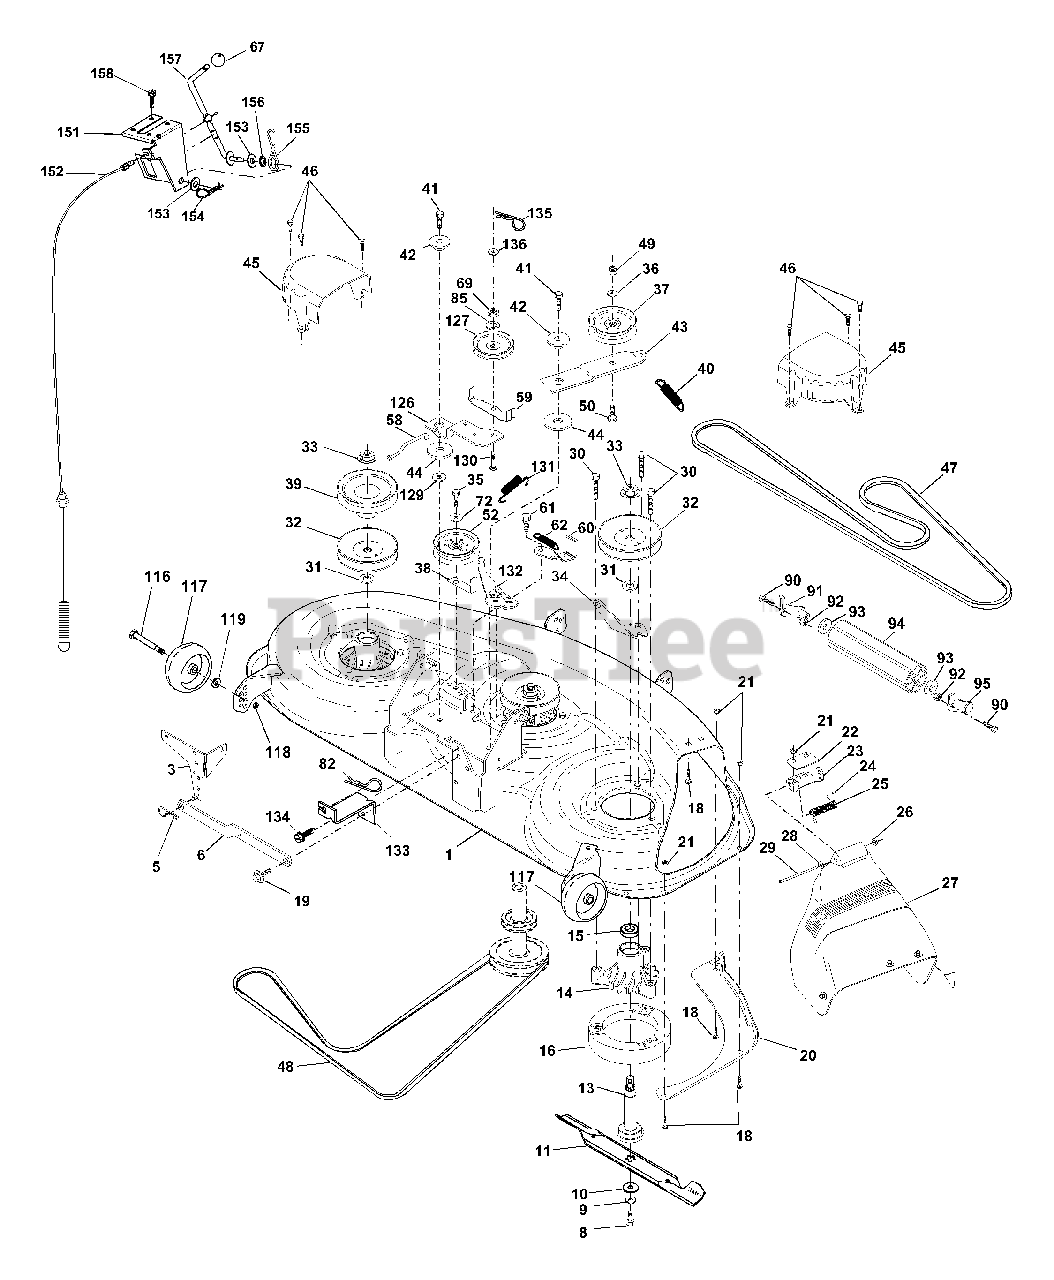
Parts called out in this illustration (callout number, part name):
1	Deck Asm., Mower 46"
3	Bracket Asm., Sway Bar
5	Retainer Spring
6	Arm, Suspension, Rear (Sway Bar)
8	Bolt, Patched 3/8-24 x 1-1/4 Gr. 8
9	Washer, Lock Hvy., Unplated 3/8
10	Washer, Hard Blade, Mower Vented
11	Blade Hi-Perf 46"
13	Shaft Asm. w/Lower Bearing
14	Housing, Mandrel
15	Bearing, Ball, Mandrel
16	Stripper, Mower Round
18	Bolt, Carriage 5/16-18 x 5/8
19	Bolt, Hex Head, Shoulder 5/16-18
20	Baffle, Vortex Mower 46"
21	Nut, Crownlock 5/16-18 UNC
22	Stiffiner, Bracket
23	Bracket, Deflector
24	Cap, Sleeve
25	Spring, Torsion, Deflector
26	Nut, Push
27	Shield, Deflector Mower
28	Washer 11/32 x 5/8 x 16 Ga.
29	Rod, Hinge
30	Screw, Thdroll Washer Head
31	Washer, Spacer Mower Vented
32	Pulley, Mandrel
33	Nut, Flg. Top Lock Cntr. 9/16
34	Anchor, Spring Deck 46"
35	Screw, Thdroll 3/8-16 x 1-3/4 Tytt
36	Washer 13/32 x 1 x 16 Ga.
37	Pulley, Idler, Flat
38	Keeper, Belt, Idler
39	Pulley, Idler, Driven
40	Spring, Secondary 44/46/50 Vent
41	Screw 3/8-16 x 1-1/4
42	Spacer, Retainer
43	Arm, Idler Secondary
44	Washer,Hardened
45	Cover, Mandrel Deck
46	Screw, Thdroll. 1/4-20 x 5/8
47	V-Belt, Mower, Secondary
48	V-Belt, Mower, Primary
49	Nut, Crownlock 3/8-16 UNC
50	Bolt, Carriage 3/8-16 x 1-1/2 Gr. 5
52	Pulley Idler
58	Rod Brake 46"
59	Guide Bolt 46" Mower Dr
60	Arm Asm Brake 46"
61	Bolt Shld 5/16-18
62	Spring Return
67	Knob Rd 3/8-16 Plstc Thds Blk
69	Nut Hex Jam 3/8-16 Unc
72	Washer 13/32 x 1 x 16 Ga.
82	Retainer Spring
85	Washer Lock 3/8
90	Bolt Fin Hex 5/16-18 x 1
91	Bracket Asm. Noseroller Lh
92	Nut Lock Hex 5/16-18
93	Washer 17/32 x 7/8 x 16 Ga.
94	Roller Nose
95	Bracket Asm. Noseroller Rh
116	Bolt, Shoulder
117	Gauge Wheel
118	Nut, Centerlock 3/8-16 UNC
119	Washer 3/8 x 7/8 x 14 Ga.
126	Arm, Idler, Primary Deck 46"
127	Pulley, Idler, V-Groove Dim. 4.25
129	Washer 13/32 x 2-3/8 x 8 Ga
130	Bolt Carriage Idler
131	Spring Return Idler
132	Arm Spring Brake Mower
133	Bracket Anchor Cable 46"
134	Screw Thdrol 5/16-18 x 3/4
135	Retainer Spring Yellow
136	Washer 9/32 x 3/4 x 16 Ga
151	Bracket Clutch Cable
152	Clutch Cable 38"/46"
153	Washer Flat 3/8" Type B
154	Spring Retainer
155	Spring Retension Q
156	SPacer Clutch Cable
157	Rod Clutch Cable 3/8"
158	Screw Hex Thd Cut 1/4-20 x 5/8
